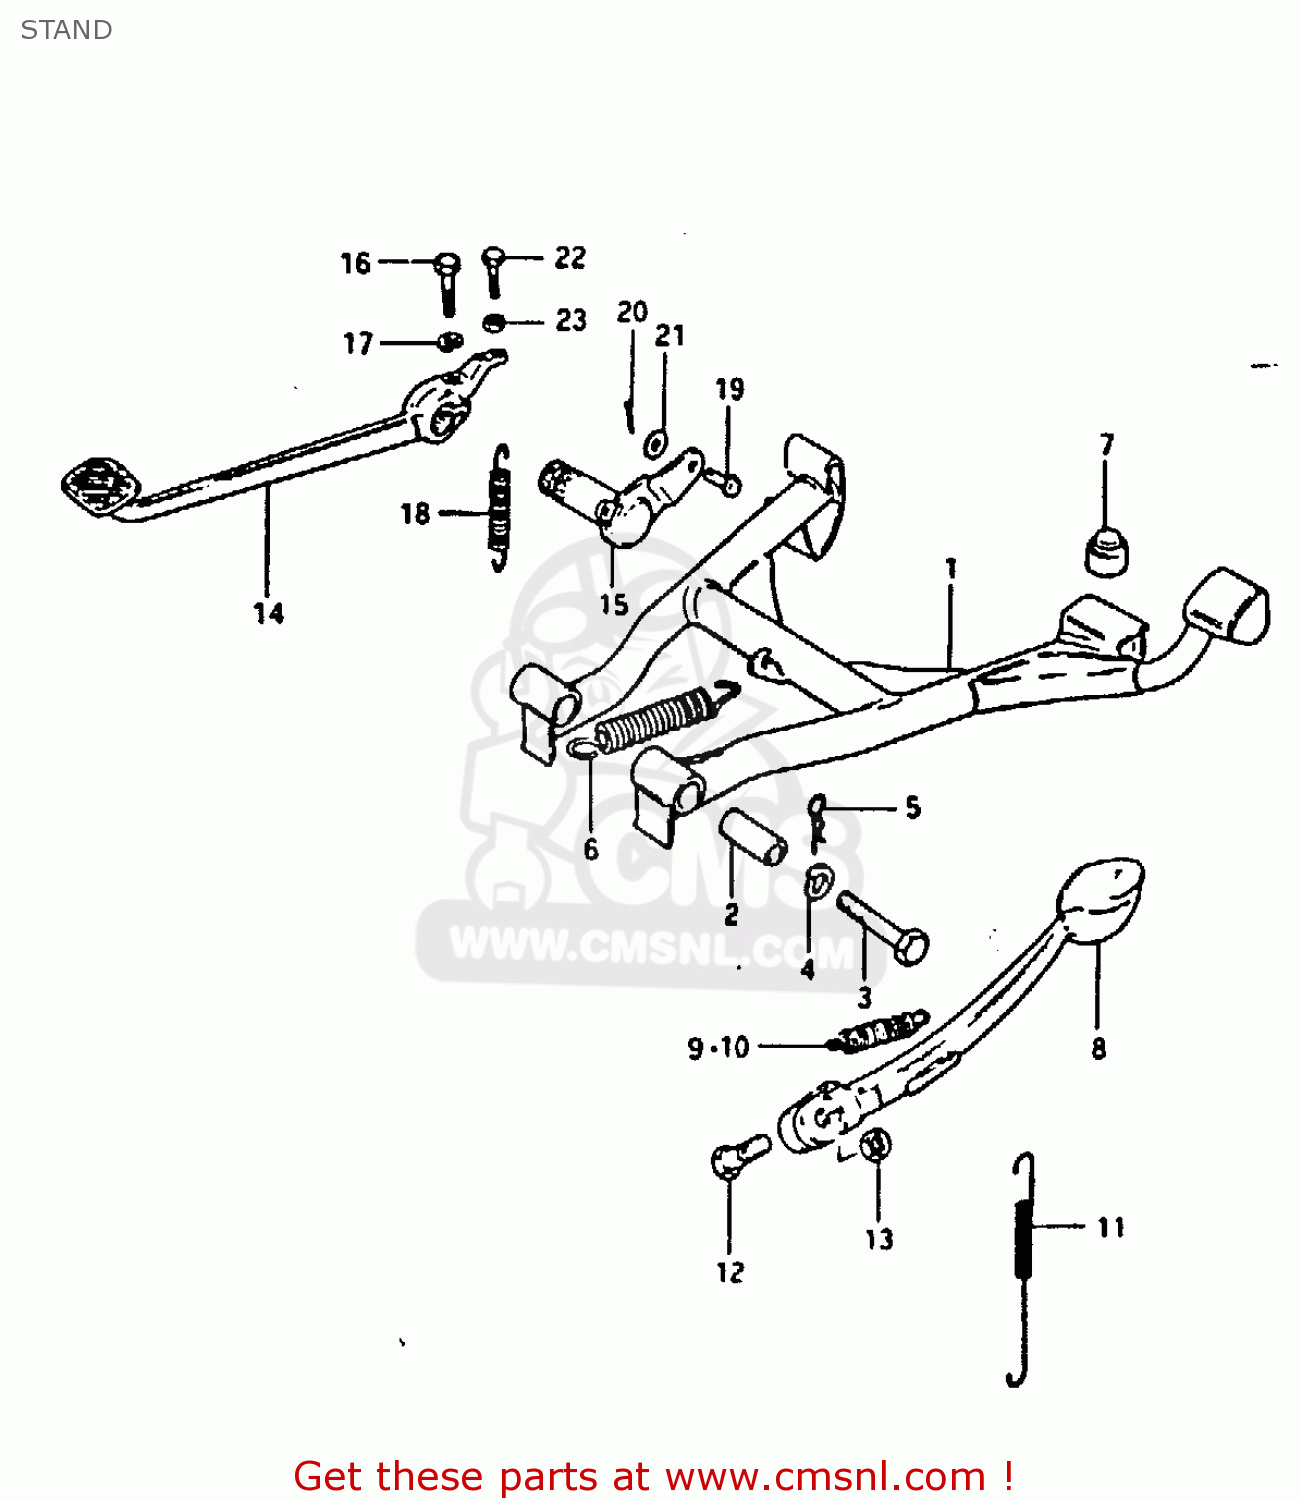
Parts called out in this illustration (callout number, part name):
1	STAND,CENTER
2	SPACER(10X16X38.8)
3	BOLT
4	LOCK WASHER
5	CLIP
6	SPRING
7	CUSHION
8	STAND,SIDE
9	SPRING
10	SPRING
11	SPRING
12	BOLT(10X30)
13	NUT
14	PEDAL,BRAKE
15	ARM,BRAKE PEDAL ROD
16	BOLT
17	LOCK WASHER
18	SPRING
19	PIN
20	PIN
21	WASHER
22	BOLT
23	NUT
